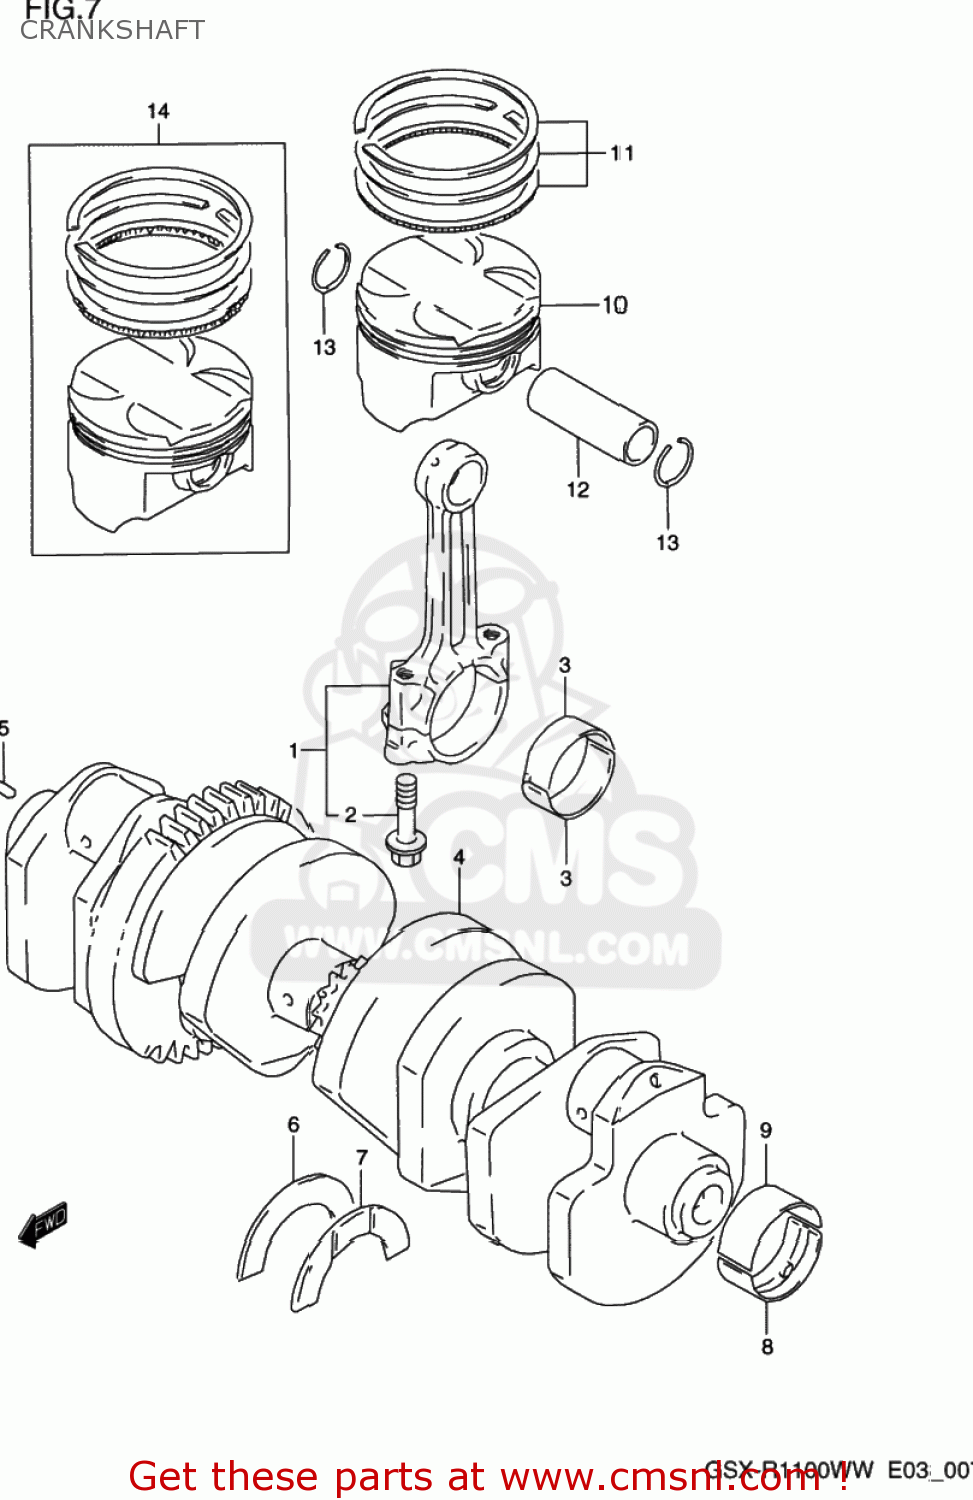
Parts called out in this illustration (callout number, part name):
1	CONNECTING ROD ASSY
2	BOLT,CONNCTING ROD
3	BEARING,CRANK PIN
4	CRANKSHAFT SET
5	PIN
6	BEARING,CRANK THRUST(GREEN)
7	BEARING,CRANK THRUST(RED)
8	BEARING,CRANKSHAFT LWR
9	BEARING,CRANKSHAFT UPR
10	PISTON
11	RING SET,PISTON
12	PIN,PISTON
13	CIRCLIP,PISTON PIN
14	PISTON SET(OS:0.5)
